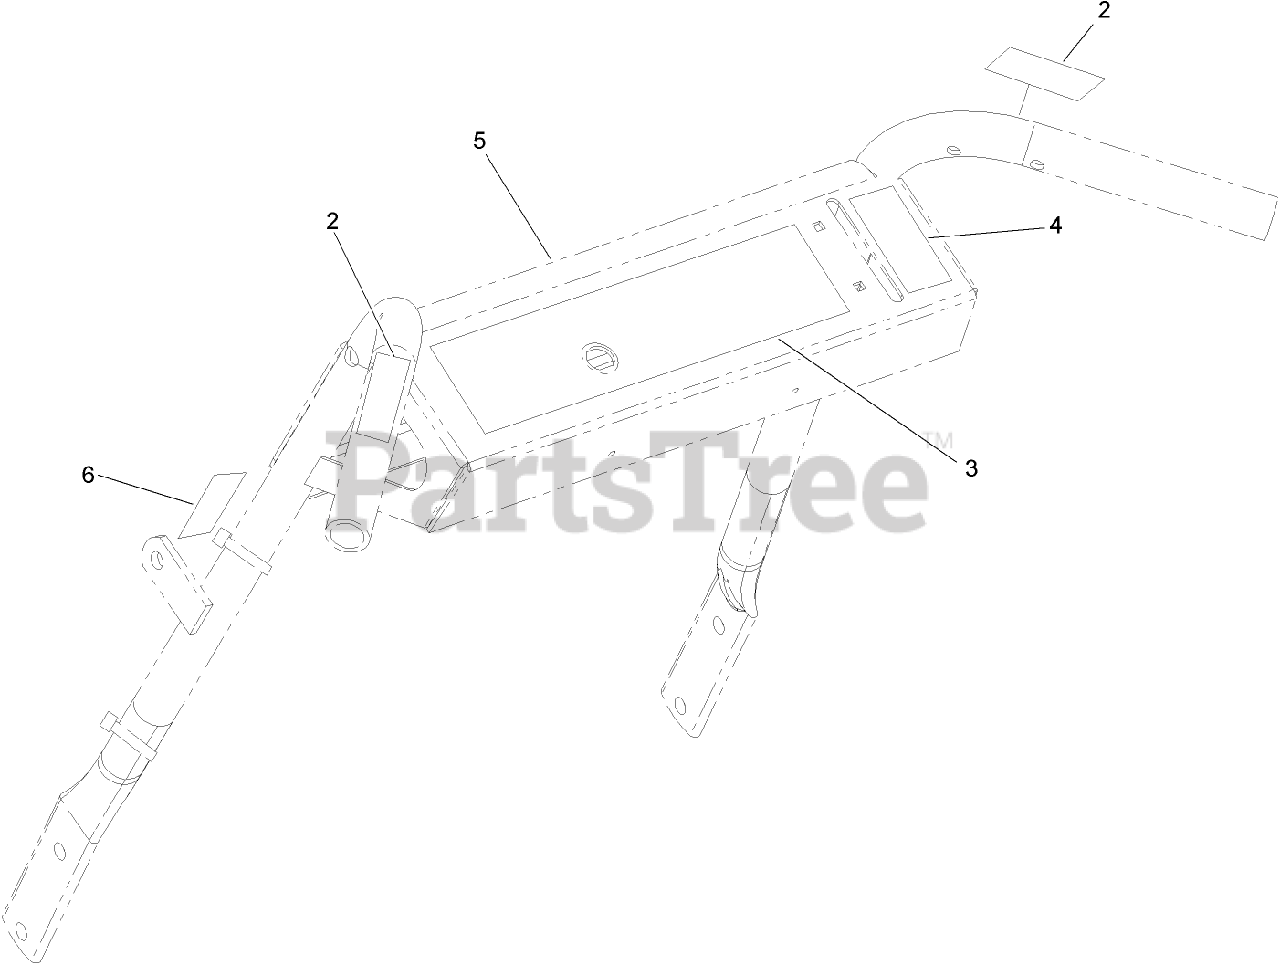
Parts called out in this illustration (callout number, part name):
2	DECAL-LOCK, NEUTRAL
3	DECAL-WARNING
4	DECAL-THROTTLE
6	DECAL-ENGAGE, DECK
